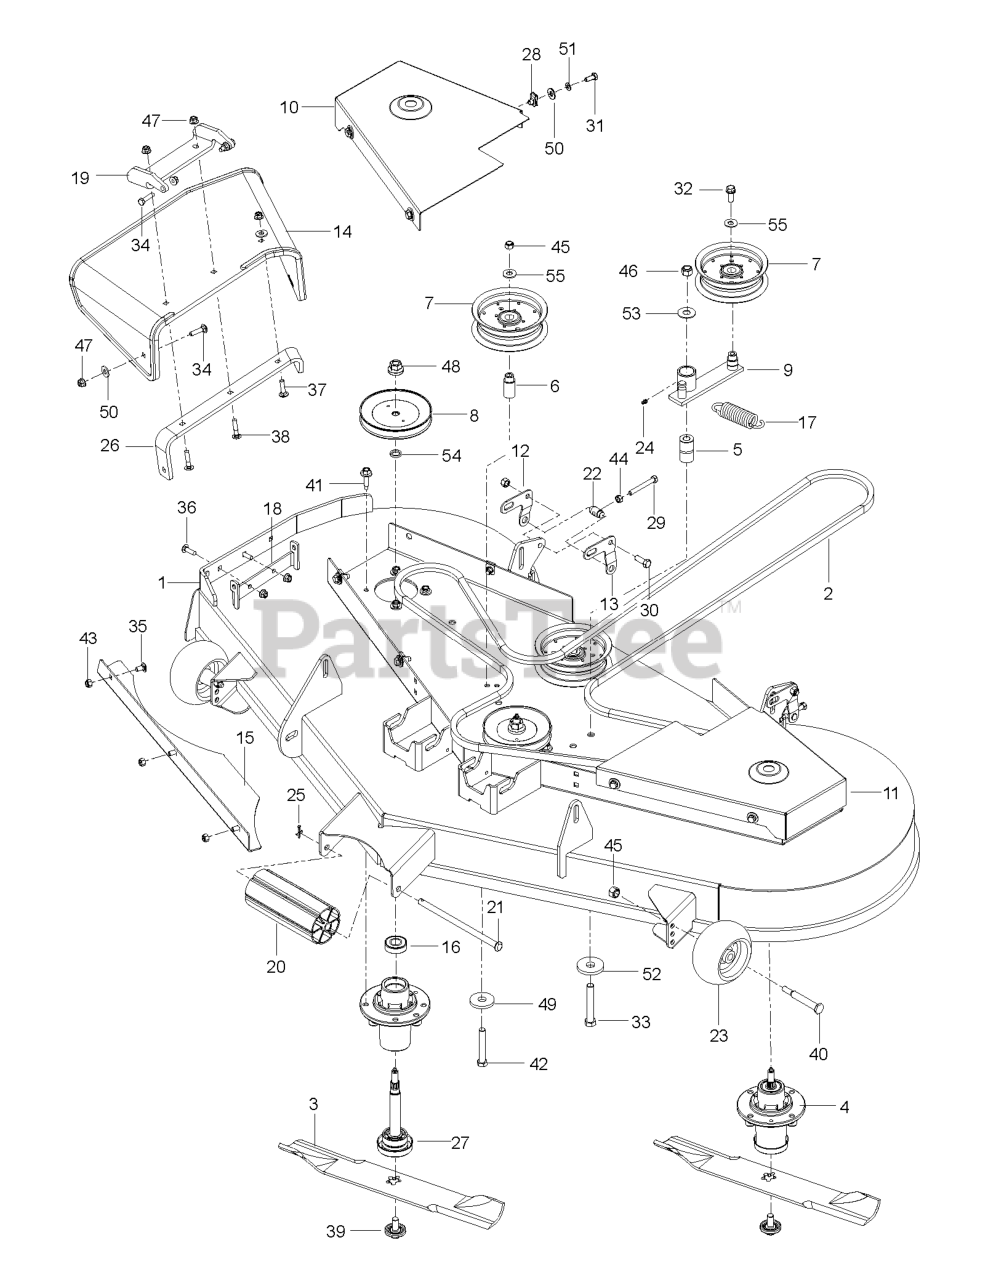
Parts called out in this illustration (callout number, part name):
1	DECK SVC MZT 61 W/DECALS ORG
2	BELT, DECK
3	BLADE, 21"
4	MANDREL ASM, CAST IRON
5	PIVOT BUSHING
6	IDLER BUSHING
7	PULLEY.IDLER.DECK
10	BELT SHIELD, RH ORANGE
11	BELT.SHIELD.LH.ORANGE
12	BRACKET.RT.PNT.MS431
13	BRACKET.LH.PNT.MS431
14	CHUTE, RUBBER DISCHARGE 52/61"
15	CONFINEMENT PLATE 61
16	BEARING.MANDREL.TOP.EXTENDED
16	BEARING
18	BRACKET.M-ZT.CHUTE(ORG)
18	BRACKET MZT CHUTE SNAPPER RED
19	PIVOT BRACKET - CHUTE
20	NOSE ROLLER 48"
21	ROD.ROLLER.NOSE.NARROW.48"
22	TRUNION, PITCH
23	WHEEL GAGE DONUT
24	ZERK
25	COTTER PIN
26	BRACKET.M-ZT.CHUTE(ORG)
26	BRACKET.REINF.CHUTE.52/61.EDIP
27	SHAFT ASM MANDREL
28	U-CLIP 5/16-18 NUT RETAINER
28	BOLT.HEX.FIN.3/8-16 X 3.GR5
29	HCS 5/16-18 X 2 1/2 TPBLT
30	HCS 3/8-16X1.GRD.5.ZD
31	HCS 5/16C X 3/4
32	4CS 3/8C X 1 SERRATED HEAD
33	HCS 1/2C X 3 1/4
34	BOLT.5/16-18X1-1/4 FULL.THREAD
35	CARRIAGE BOLT 5/16C X 5/8"
36	BOLT CRT
36	RHSSNB 5/16C X 1.0
37	BOLT, CARRIAGE 5/16X1-1/4
38	RHSNB 5/16-18 X 1-1/2 GR 5 ZD
39	BOLT.WASHER.ASM.7/16-2
40	BOLT, SHOULDER
41	BOLT.HEX.WASHR.HED.313-18X1.19
42	NUT.FLANGE.LOCK.TOP
42	BOLT.HEX.FIN.3/8-16 X 3.GR5
43	NUT 5/16 NYLOC
44	NUT 5/16C HEX
45	NUT 3/8-16 NYLOC
46	NUT.LK.W/WSH.1/2.
46	NUT 1/2-13 HEX NYLOC ZD
47	5/16-18 NYLOC FLANGE NUT
49	SPINDLE WASHER
50	WASHER 5/16 FLAT
50	WASHER.5/16.FLAT.STE.STD.
51	WASH 5/16 DISC SPRING ZD
52	WASHER, SUPPORT
53	WASHER 1/2 FLAT
53	WASHER.9/16 X 1 3/8 X 12 GA.
54	WASHER.SPACER.MANDREL
55	RP WASHER 3/8 FLAT
